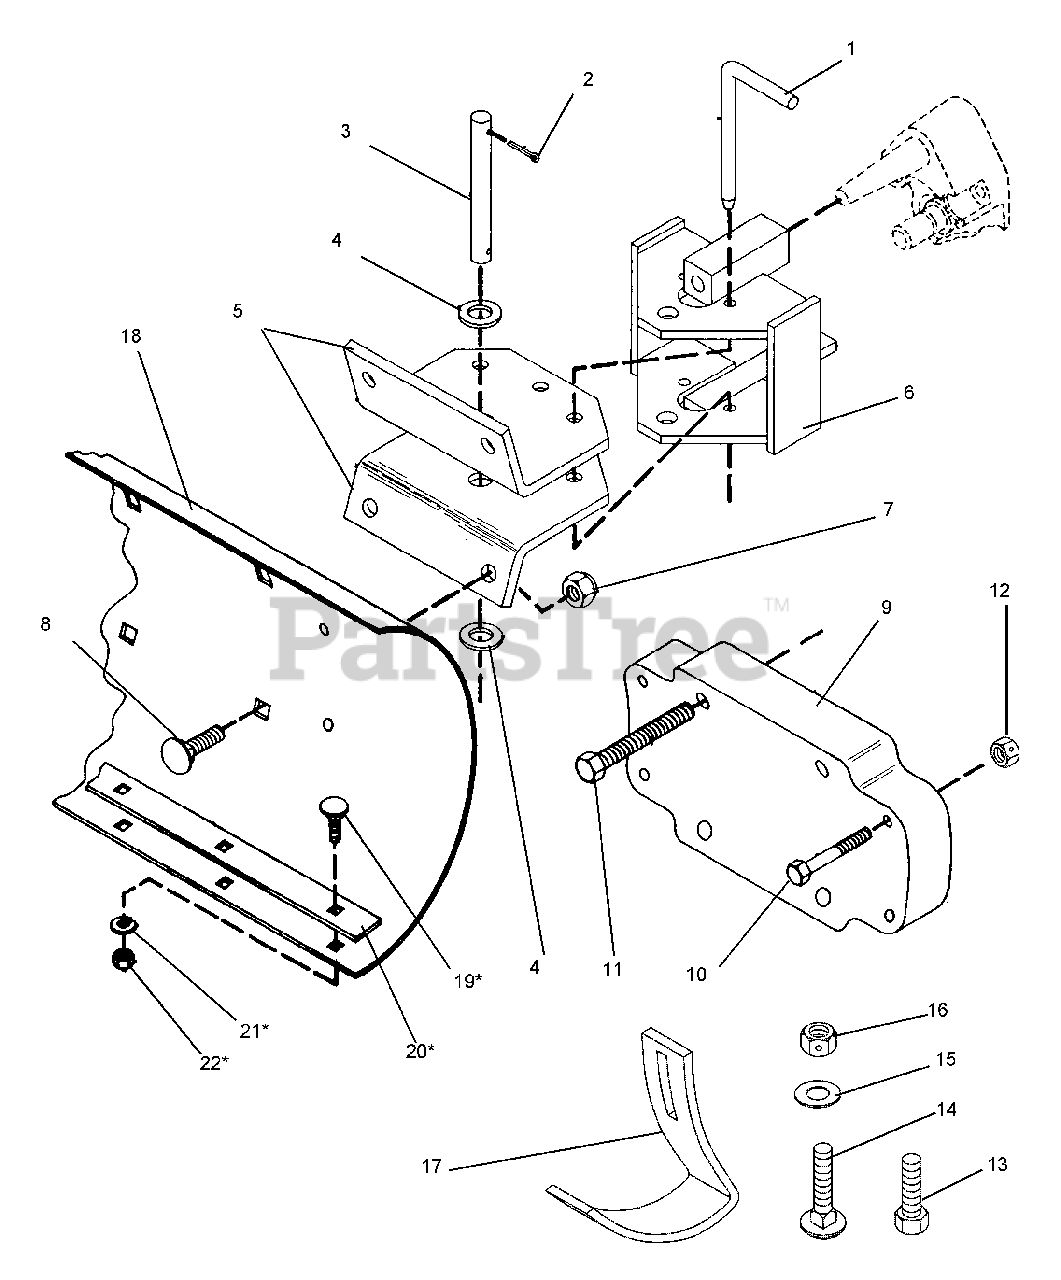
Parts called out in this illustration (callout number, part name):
9	Blade Weight
10	3/8" x 2-3/4" Hex Bolt
11	1/2" x 3-1/4" Hex Bolt
12	3/8" Center Locknut
